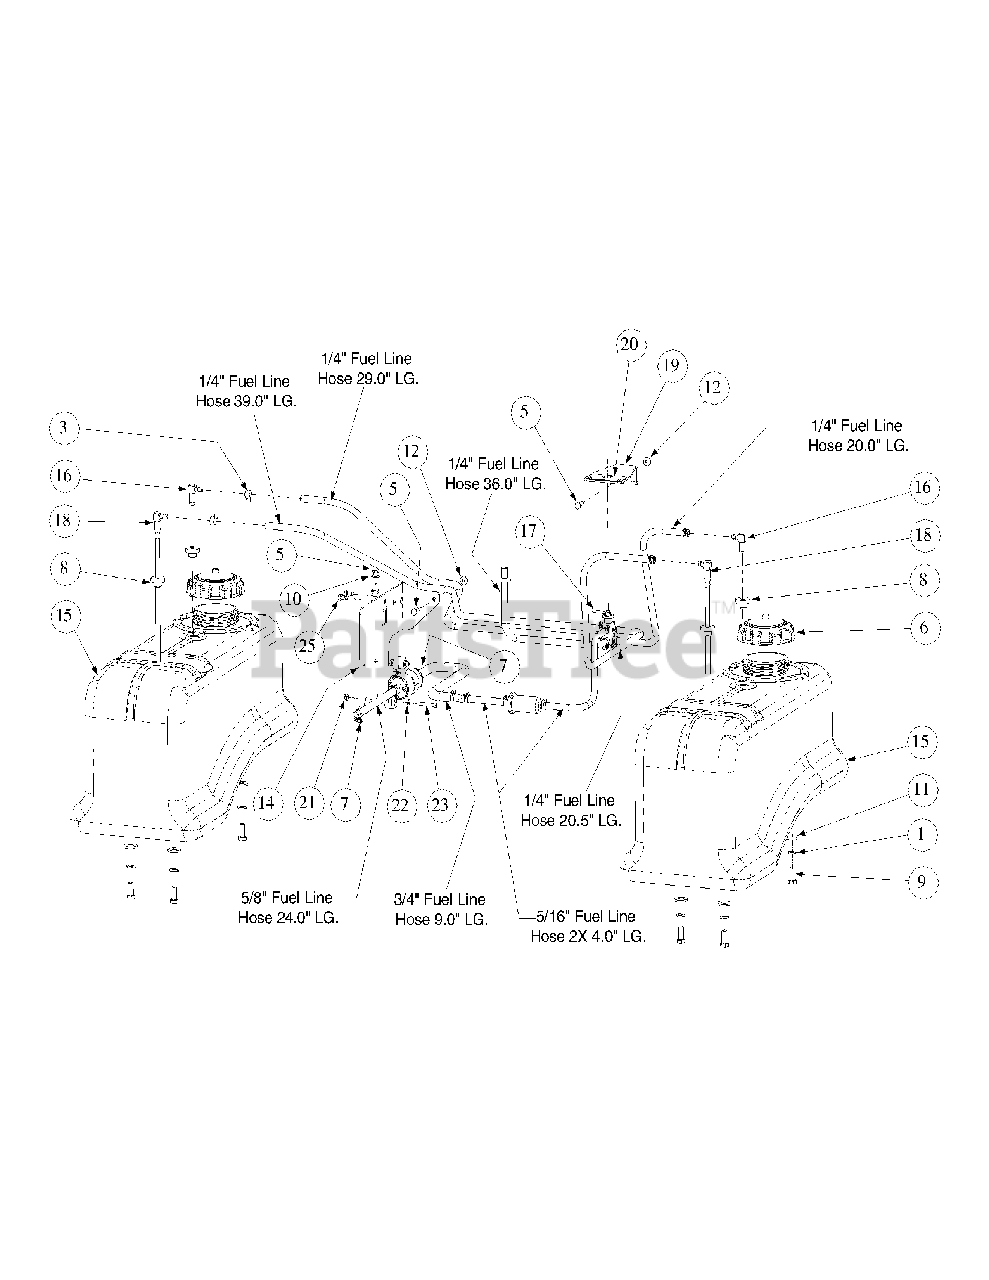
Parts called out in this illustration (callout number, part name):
1	Lock Washer, 3/8
2	Hose, 1/4" Fuel Line 144.5"
3	Clamp, Union
4	Cable Tie
5	Hex Cap Screw, 1/4-20 x 3/4
6	Fuel Cap, 3.5
7	Hose Clamp
8	Fuel Tank Grommet
9	Hex, Cap Screw, 3/8-16, .88
10	Washer, 5/16
11	Flat Washer, .406 ID, 1.0 OD, .105
12	Hex Flange Lock Nut, 1/4-20
13	Fuel Hose, .38 ID x .625 OD, 24"
14	Pump Mounting Bracket
15	Fuel Tank
16	Fuel Fitting, Return
17	Shut Off Fuel Valve
18	Fuel Fitting, Pickup
19	Fuel Valve Mounting Bracket
20	Decal, Fuel Tank Shut Off
21	Nut, 10-24, Nylon Insert
22	Washer, 3/16
23	Socket Head Screw, 10-24 x 1.25
24	Fuel Hose, .50 ID x .75 OD, 9"
25	Self Tapping Screw, 1/4-20 x .50
26	Hose, 5/16" Fuel Line 8"
